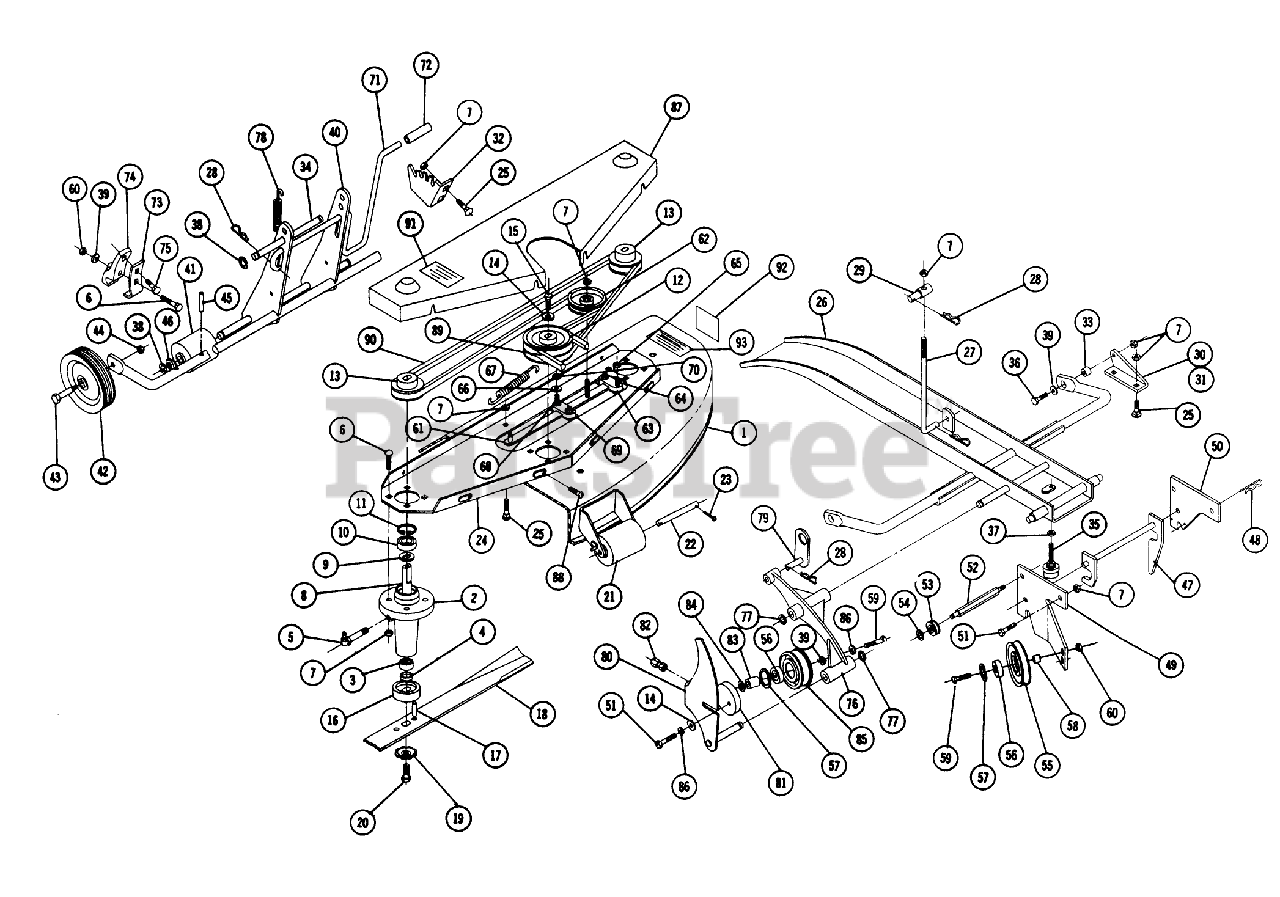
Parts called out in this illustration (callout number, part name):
6	Bolt Carriage 3/8-16 x 1
7	3/8-16 E.S.
9	WASHER
11	INT SNAP RING
14	WASHER
15	Bolt 3/8-16 x 7/8
17	SPIROL ROLL PIN
20	Bolt 3/8-16 x 7/8
23	Cotter Pin
25	Bolt-3/8-16 x 3/4
28	Hairpin
29	TRUNNION-LIFT
30	Bracket-Deck R.H.
31	Bracket-Deck L.H.
36	Bolt 3/8-16 x 1
37	Nut, 5/16-18
39	Washer
40	Ass-y Gage Wheel Support
43	BOLT-SHOULDER
44	3/8-16 Jam Nut
45	Roll Pin
46	Washer
48	Hairpin
49	MOUNTING BRACKET *R
51	Bolt 3/8-16 x 1
54	Lock Rod
56	BEARING
57	INTERNAL SNAPRING
59	Bolt, 3/8-16 x 1/2
64	Bolt-5/16-18 x 1/4
65	Nut 5/16-18
66	Washer
67	SPRING *R
68	Bolt-5/16-18 x 1 1/2
70	Nut-Nylok
72	Grip Handle
74	SUPPORT AXLE
75	Bolt-Carriage
78	Spring
80	ASSEMBLY CAM LEVE *R
84	Lockwasher-3/8 Int. Tooth
86	Lockwasher
88	Bolt 1/4-20 x 3/8
90	V-BELT
91	Decal Belt Installation
